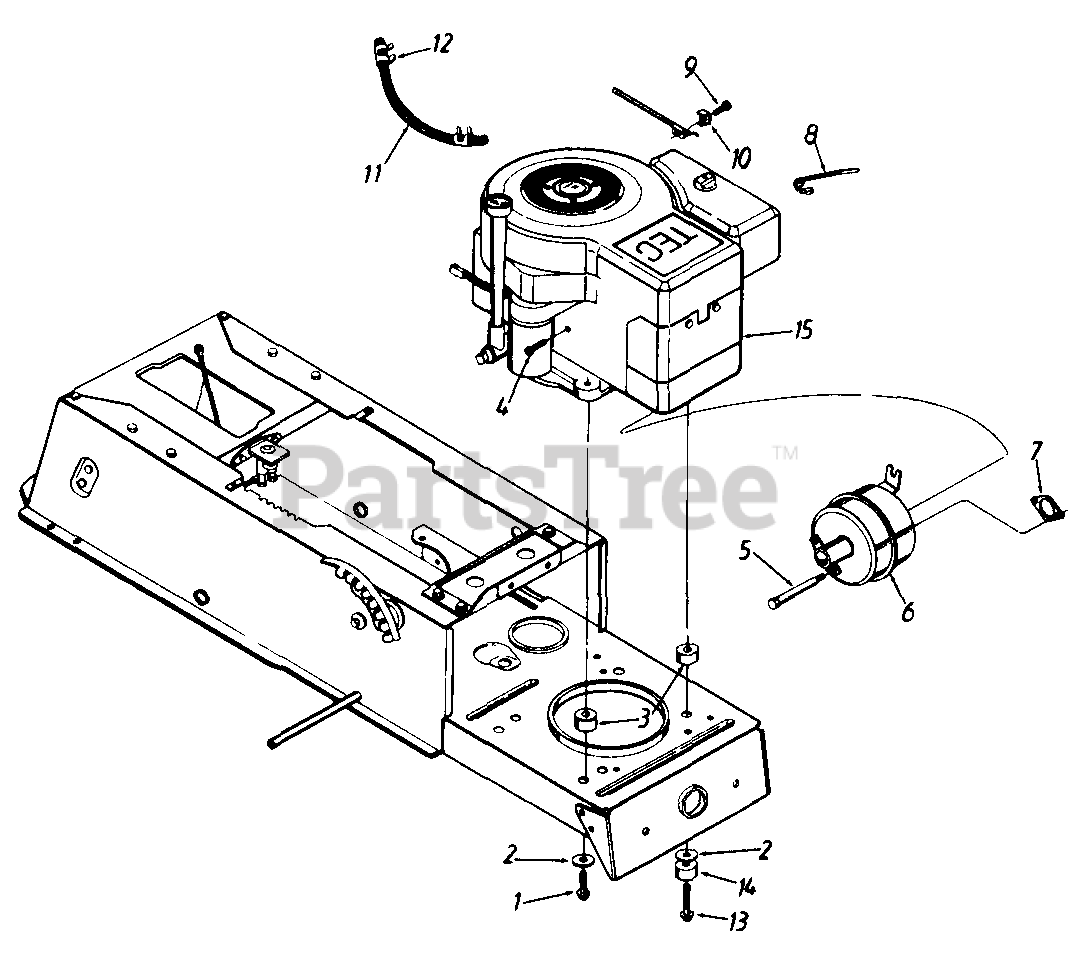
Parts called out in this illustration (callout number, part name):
1	Hex L-Wash. TT-Tap Scr. 3/8-16 x 1.5" Lg.
2	Fl-Wash. 3/8" I.D. x 1-1/4" O.D.
4	Pan Hd. Mach. Scr. 5/16-18 x .75" Lg.
5	Shld. Bolt 7/16" Dia. x 3-5/8" Lg. (12 & 12.5 H.P. Only)
6	Muffler (12 & 12.5 H.P. Only)
7	Exhaust Gasket (12 & 12.5 H.P. Only)
8	Cable Tie
9	Hex Sems Scr. #10-32 x 5/8" Lg.
10	Casing Clamp
11	Fuel Line
12	Hose Clamp
13	Hex L-Wash. TT-Tap Scr. 3/8-16 x 2.5" Lg. (16 H.P. Only)
14	Shld. Spacer.38" I.D. x 1.25" Q.D. (16 H.P. Only)
15	Engine
